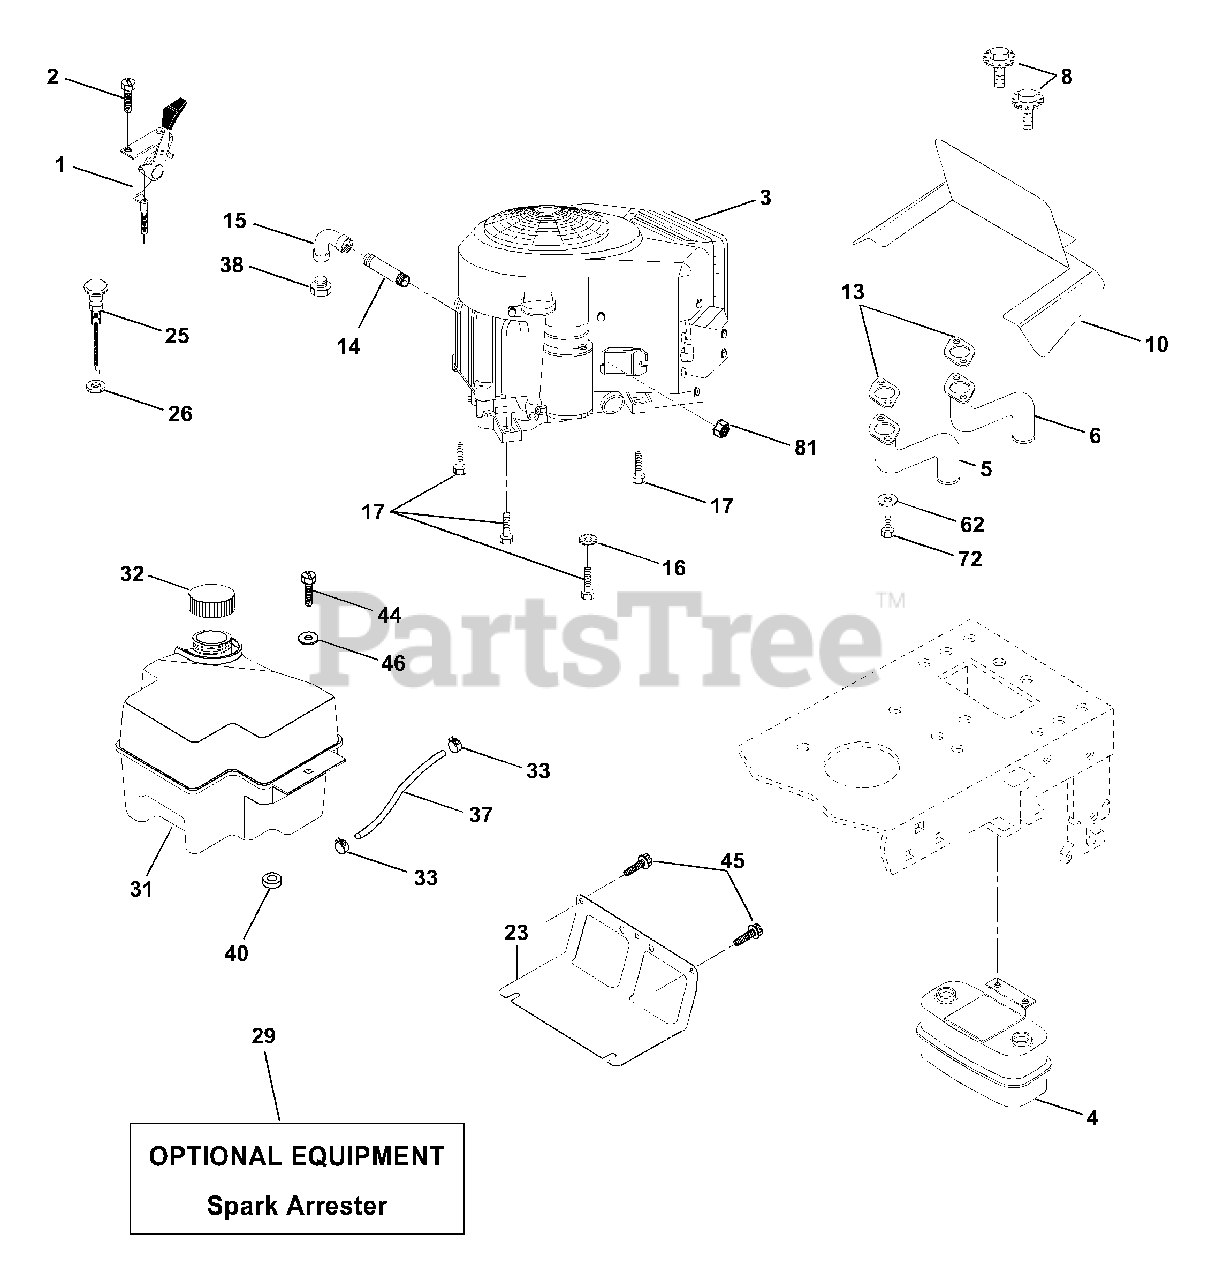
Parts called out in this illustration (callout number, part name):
1	Control, Throttle
2	Screw Hex Thd Cut 1/4-20 x 5/8
4	Muffler, Asm. Twin Lo-Tone
5	Pipe Exhaust Intek 20 RH
6	Pipe Exhaust Intek 20 LH
8	Bolt 5/16-18 UNC x 3/4
10	Shield Browing B&S Intek II
13	Muffler Gasket
14	Nipple, Pipe
15	Elbow, Standard 90°, 3/8-18 NPT
16	Washer, Lock Ext tooth 3/8
17	Screw Thdrol 3/8-16 x 1-1/2
23	Shield, Browning/Debris Guard
25	Control Choke
26	Nut Keps 3/8-24 UNF
29	Arrester, Spark
31	Tank, Fuel
32	Cap Gauge, Fuel
33	Clamp, Hose Blk
37	Line, Fuel 7.5
38	Plug, Oil Drain
40	Bushing Snap Nyl Blk Fuel Line
44	Screw Hex Wsh Thdrol 1/4-20 x 3/4
45	Screw Hex Wsh Thdrol 3/8-16 x 3/4
46	Washer 9/32 x 7/8 x 16 Ga.
62	Washer Lock Hvy Hlcl Spr 5/16
72	Screw Hex Hd Cap 5/16-18 x 3/4
81	Nut Keps Hex 1/4-20 Unc
